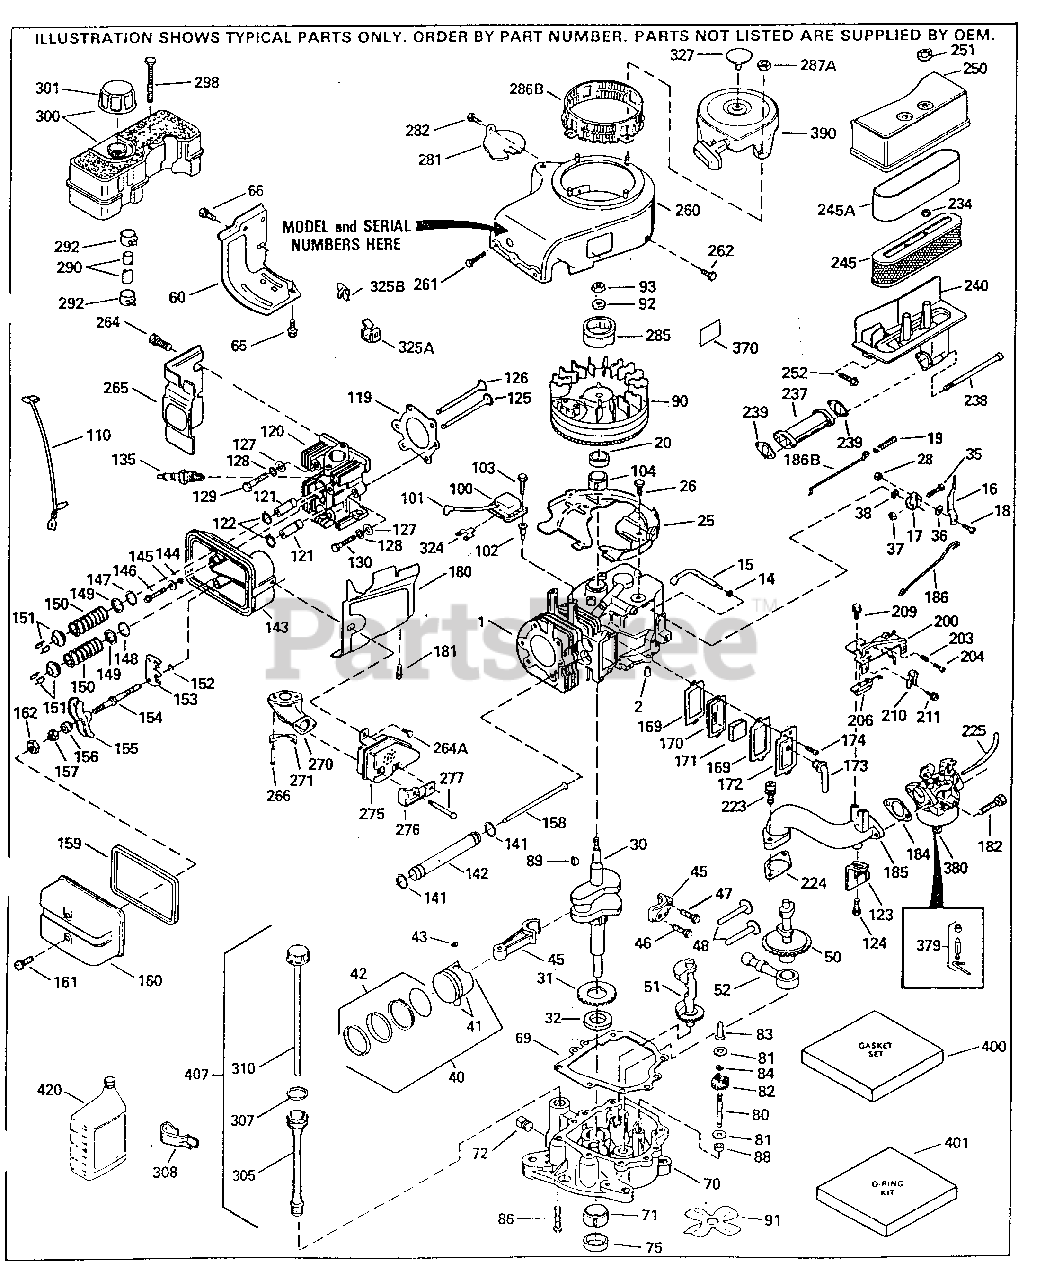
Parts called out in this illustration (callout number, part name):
1	"Cylinder (Incl. 2 & 20) 3-5/16" Bore
2	Dowel Pin
14	Flat Washer
15	Governor Rod
16	Governor Lever
17	Governor Lever Clamp
18	Screw, 8-32 x 5/16"
19	Extension Spring
20	Oil Seal
25	Blower Housing Baffle
26	Screw, 1/4-20 x 5/8"
28	Lock Nut, 8-32
30	Crankshaft
31	Counterbalance Gear
32	Shim Washer (.015") (Use as required)
35	Screw, 10-32 x 3/4"
36	Lock Washer #8
37	Lock Nut, 10-32
38	Retaining Ring
40	Piston, Pin & Ring Set (Std.)
40	Piston, Pin & Ring Set (.010" OS)
40	Piston, Pin & Ring Set (.020" OS)
41	Piston & Pin Ass'y. (Std.) (Incl. 43)
41	Piston & Pin Ass'y. (.010" OS) Incl. 43
41	Piston & Pin Ass'y. (.020" OS) Incl. 43
42	Ring Set (Std.) (3-5/16")
42	Ring Set (.010" OS)
42	Ring Set (.020" OS)
43	Piston Pin Retaining Ring
45	Connecting Rod Ass'y. (Incl. 46 & 47)
46	Connecting Rod Bolt
47	Connecting Rod Bolt
48	Valve Lifter
50	Camshaft (MCR)
51	Counterbalance Weight
52	Oil Pump
60	Blower Housing Extension
65	Screw, 10-24 x 1/2"
66	Screw, T-30, 1/4-20 x 1/2"
69	* Mounting Flange Gasket
70	Mounting Flange (Incl. 72, 72A, 75 & 80)
72	Oil Drain Plug
75	Oil Seal
80	Governor Shaft
81	WASHER
82	Governor Gear Assembly
83	Governor Spool
84	Retaining Ring
86	Screw, 1/4-20 x 1-3/16"
88	Spacer (Incl. 81)
89	Flywheel Key
90	Flywheel (3 amp w/ring gear)
92	Lock Washer
93	Flywheel Nut
100	Solid State Ignition
101	Spark Plug Cover
102	Solid State Mounting Stud
103	Screw, Torx T-15, 10-24 x 1"
119	* Cylinder Head Gasket
120	Cylinder Head
121	Valve Guide Kit (Incl. 2 of 122)
122	Retaining Ring
123	Intake Pipe Brace
124	Screw, 1/4-20 x 5/8"
125	Exhaust Valve (Std.)
125	Exhaust Valve (1/32" OS)
126	Intake Valve (Std.)
126	Intake Valve (1/32" OS)
128	Belleville Washer
129	Screw, 5/16-18 x 1-3/8"
130	Screw, 5/16-18 x 1-3/4"
135	Resistor Spark Plug (RL-86C)
141	"O" Ring
142	Push Rod Tube
143	Rocker Arm Housing
144	"O" Ring
146	Screw, 1/4-20 x 29/32"
147	"O" Ring (Intake)
148	"O" Ring (Exhaust)
149	Valve Spring Cap
150	Valve Spring
151	Valve Spring Keeper
152	"O" Ring
153	Push Rod Guide
154	Rocker Arm Stud
155	Rocker Arm
156	Rocker Arm Bearing
157	Lock Nut (Incl. 162)
158	Push Rod
159	"O" Ring (Incl. 161)
160	Rocker Arm Housing
161	Screw, Torx T-20, 8-32 x 1/2"
162	Jam Nut
169	* Valve Cover Gasket
170	Breather Body
171	Breather Element
172	Valve Cover
173	Breather Tube
174	Screw, 10-24 x 1/2"
180	Blower Housing Extension
181	Screw, 10-24 x 1/2"
182	Screw, 1/4-20 x 27/32"
184	* Carburetor To Intake Pipe Gasket
185	Intake Pipe
186	Governor Link
203	Compression Spring
204	Screw, 5-40 x 7/16"
209	Screw, 10-32 x 7/16"
210	Conduit Clip
211	Screw, 10-32 x 3/8"
223	Screw, 5/16-18 x 7/8"
224	* Intake Pipe Gasket
234	Nut & Lock Washer, 1/4-20 (Sealing)
237	Air Filter Adapter
238	Screw, 10-32 x 5-1/4"
239	* Carburetor Gasket
240	Air Cleaner Body
245	Air Filter (Incl. 234) also available in Packaged Part #740015B
245A	Pre-Cleaner Air Filter also available in Packaged Part #740015B
250	Air Cleaner Cover
251	Wing Nut, 1/4-20
252	Screw, 1/4-20 x 1"
261	Screw, T-30, 1/4-20 x 1/2"
262	Screw, T-40, 5/16-24 x 21/32"
264	Screw, 5/16-18 x 5/8"
264A	Screw, T-30, 1/4-20 x 1/2"
265	Cylinder Head Cover
266	Screw, 5/16-18 x 1-1/4"
270	Exhaust Manifold
271	Locking Plate (Manifold)
275	Muffler
276	Locking Plate
277	Screw, 5/16-18 x 4-1/2"
290	Fuel Line (16" or 40cm)
292	Fuel Line Clamp
298	Screw, 10-32 x 35/64"
305	Oil Fill Tube
307	"O" Ring
308	Fill Tube Clip
310	Dipstick
325B	Wire Clip
370	Instruction Decal
379	Inlet Needle, Seat & Clip Ass'y.
380	Carburetor (Incl. 184) (Refer to Divi sion 5, Section A, page A4-8 or Fiche 12, Grid F-7for breakdown)
390	Rewind Starter Refer to Division 5, S ection C, page 30 or Fiche 12, Grid G -9 for breakdown
400	Gasket Set
401	"O'' Ring Kit (Also incl. in 400) (In cl. 141, 144, 147, 148, 152, 157, 159 )
420	SAE30 4-Cycle Engine Oil (Quart)
